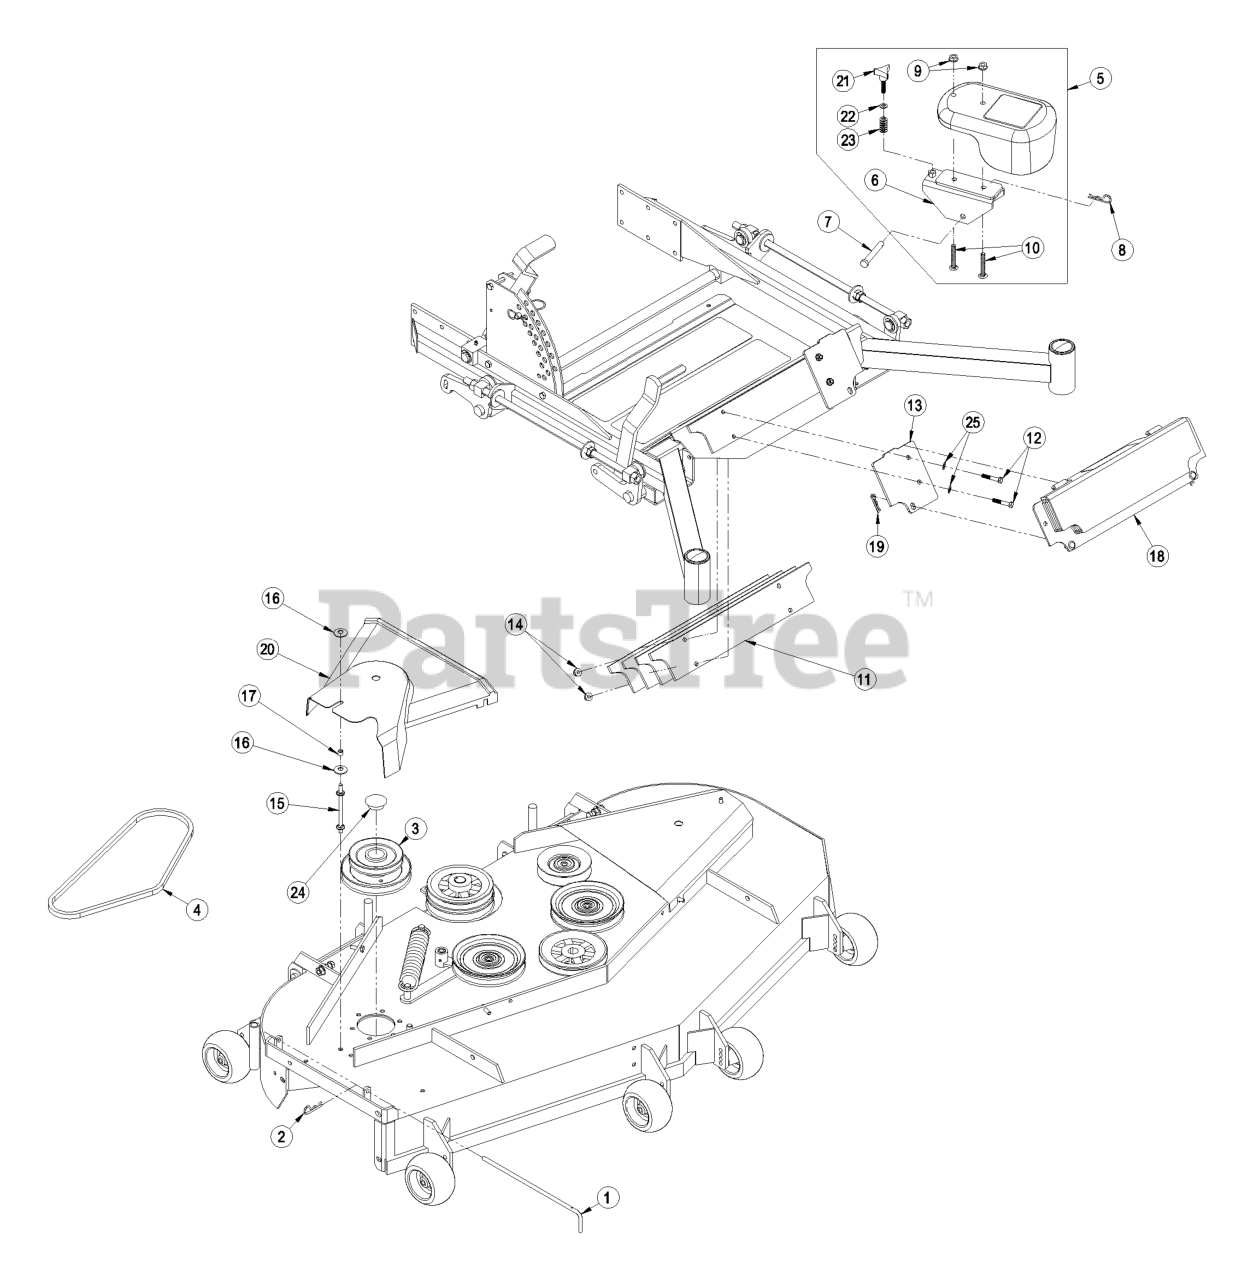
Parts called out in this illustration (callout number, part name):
1	PIN, CHUTE PIVOT
2	PIN-COTTER
3	JACKSHAFT, LZUV60
4	BELT, BLOWER DRIVE 60
5	ASM, WEIGHT 2.0" 70 POUND
6	WLD, BRACKET 2.0 ARM
7	PIN-CLEVIS
8	PIN-COTTER
9	NUT-HHF, WHIZ
10	BOLT, SQUARE HEAD YZ
11	PLATE, WEIGHT
12	SCREW-HH
13	PLATE, WEIGHT MOUNTING
15	STUD,BELT SHIELD 4 INCH
16	WASHER-SPRING
18	ASM, WEIGHT PLATE WITH DE
19	PIN-HAIR
20	COVER, BELT 60
22	WASHER-FLAT
24	PLUG, BLACK NYLON 1.75
25	WASHER-PLAIN
